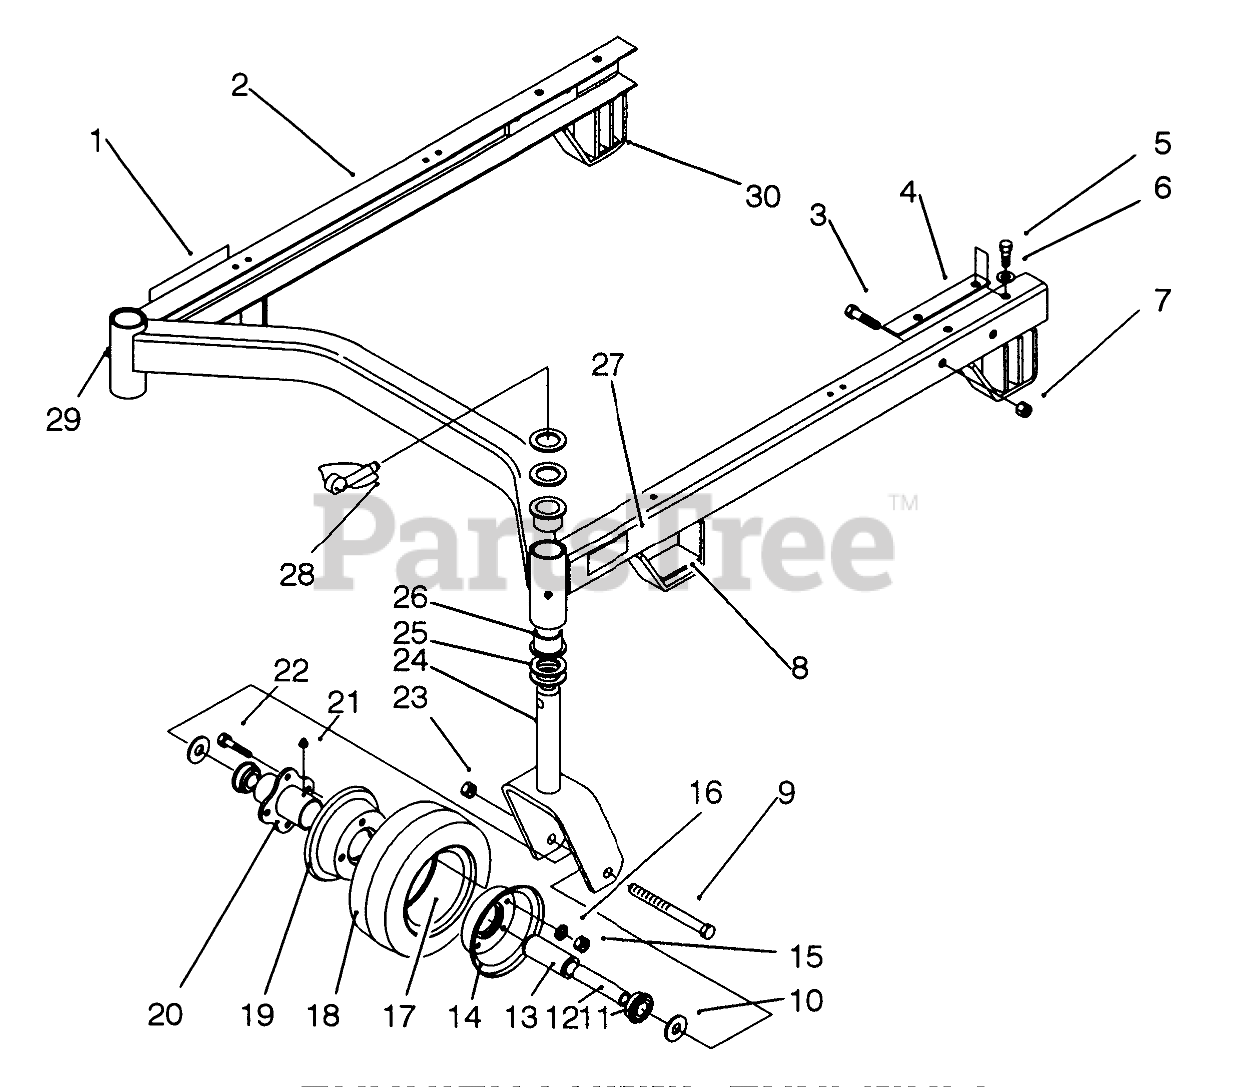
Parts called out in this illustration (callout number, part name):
1	DECAL-HOC, LH
2	Frame-Suspension Ass-y
3	SCREW-HH
4	SHIM-CARRIER
5	SCREW W/PATCH
6	WASHER-FLAT
7	NUT-LOCK, CONE
8	CUSHION-RUBBER
9	SCREW-HH
10	WASHER-FLAT
11	BEARING-OUTSIDE
12	SPANNER-TIRE
13	BEARING-ROLLER
14	MALE WHEEL HALF
15	NUT-HEX
16	WASHER-LOCK
17	TUBE-INNER (W/VALVE)
19	FEMALE WHEEL HALF
20	HUB-CENTER
21	FITTING-GREASE
22	WHEEL BOLT
23	NUT-HEX
24	Castor Fork
25	WASHER-THRUST
26	Bushing
27	DECAL-HOC, RH
28	PIN-LYNCH
29	FITTING-GREASE
30	CUSHION-RUBBER
